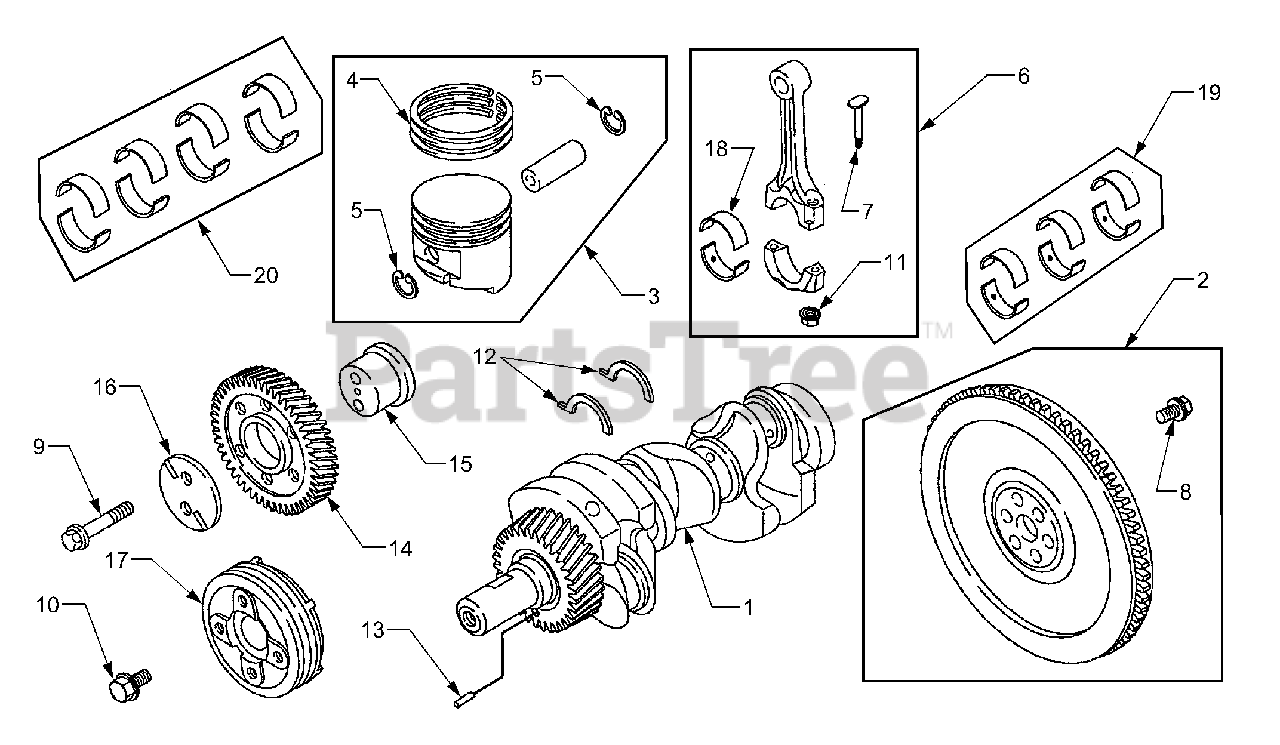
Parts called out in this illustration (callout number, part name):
1	Crankshaft
3	Piston Assembly, Standard
4	Ring Set, Standard
5	Lock Ring, Piston Pin
6	Rod, Connecting
7	Screw, Connecting Rod
8	Screw, Hex, 10mm
9	Screw, Hex, 8mm
10	Screw, Hex
12	Washer, Thrust, Standard
13	Pin, Locating
14	Gear, Drive
15	Shaft, Gear
16	Plate, Idler Gear
17	Pulley, Crankshaft
18	Bearing, Rod Standard
19	Bearing Set, Rod Standard
20	Bearing Set, Main Standard
